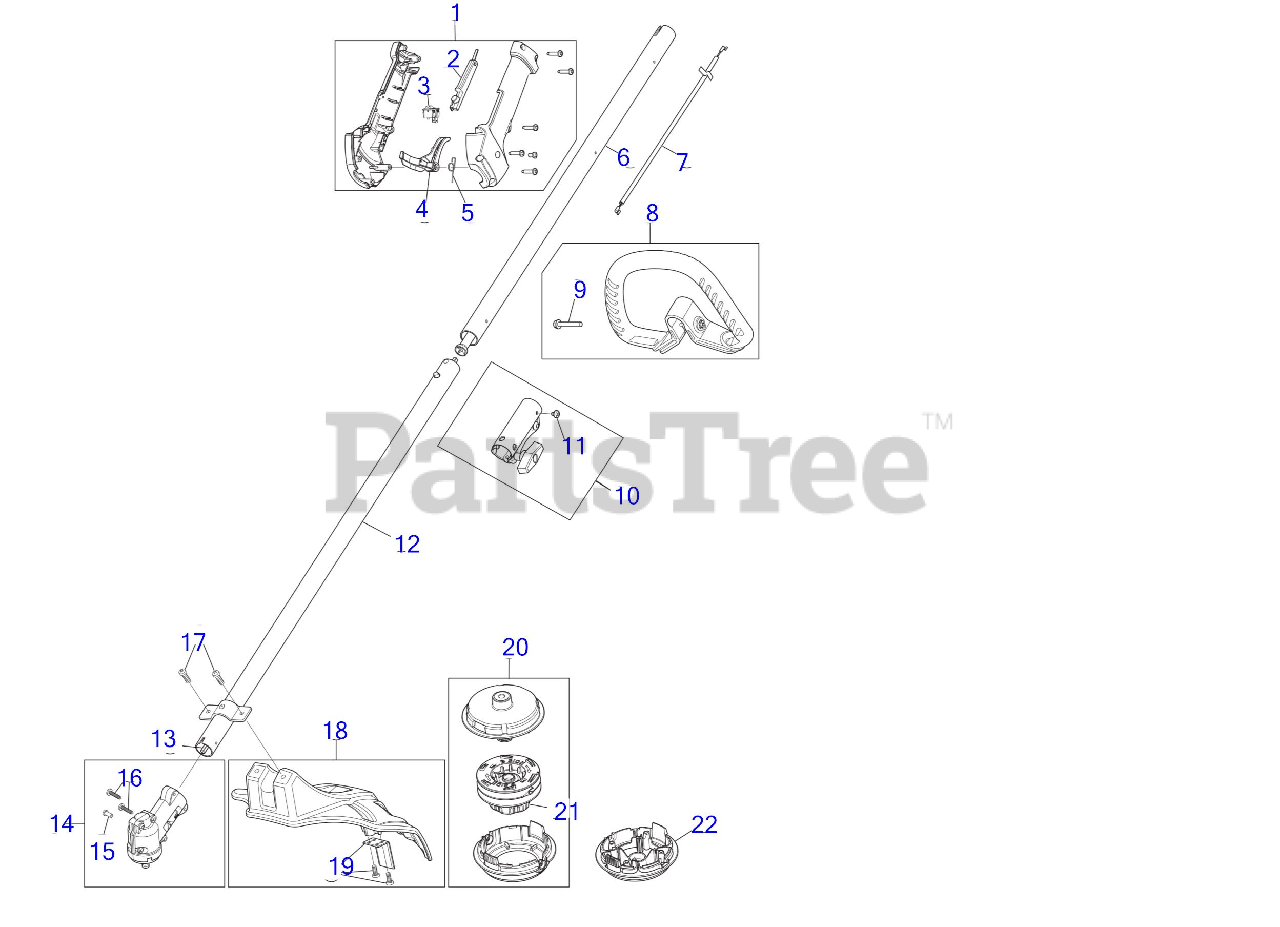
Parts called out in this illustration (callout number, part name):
1	Throttle Housing Assembly includes 2 - 5)
2	Throttle Trigger Lock-Out
3	Throttle Switch Assembly
4	Throttle Trigger
5	Throttle Trigger Spring
6	Upper Drive Shaft Assembly
7	Throttle Cable
8	D-Handle Assembly includes 9)
10	Split Boom Coupler includes 11)
11	Coupler Anti-Rotation Screw
12	Lower Drive Shaft Housing
13	Lower Flexible Drive Shaft
14	Gearbox Assembly includes 15 and 16)
15	Anti-Rotation Screw
16	Gearbox Mounting Hardware
17	Shield Mounting Screws
18	Shield Assembly includes 19)
19	Blade Assembly
20	Cutting Head Assembly includes 21)
22	Cap Assembly (with Plug)
